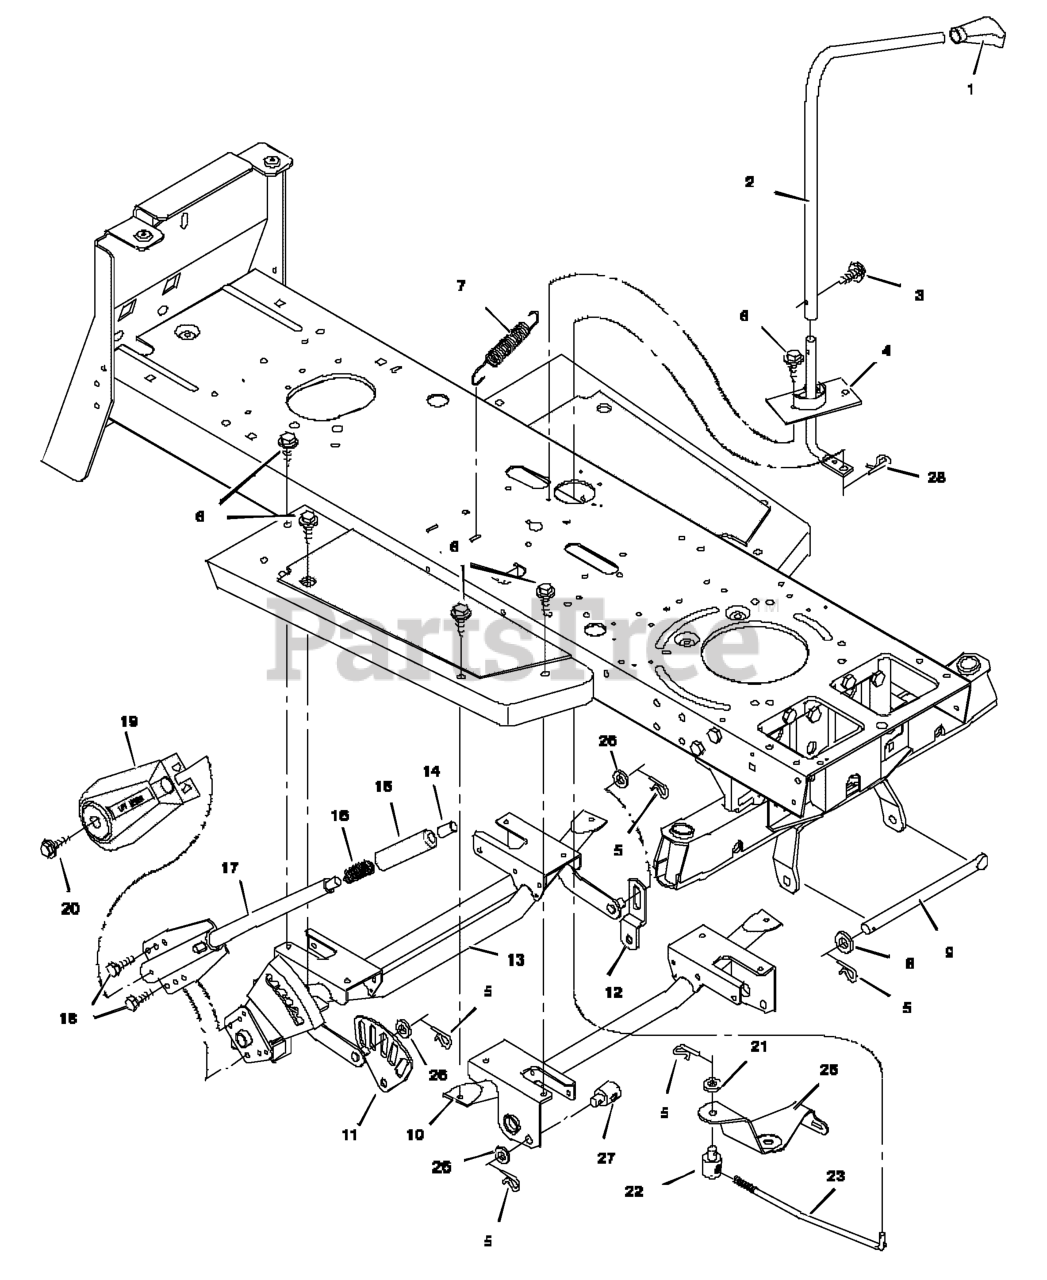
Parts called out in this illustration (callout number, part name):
1	Grip
2	Lever, Blade Control
3	Screw, Hex
4	Control Assembly, Blade
5	Pin, Hair
7	Spring, Extension
9	Pin, Pull
10	Support Assembly, Front
11	Plate, Adjuster
12	Link, Suspension
13	Support, Lifter
14	Button, Push
16	Spring, Compression
17	Handle Assembly
19	Cover, Lift Lever
22	Nut, Adjusting
23	Rod, Blade Control
24	Washer
25	Bracket, Pivot
27	NUT, Adjusting, 1/2-13
28	Pin, Hair
